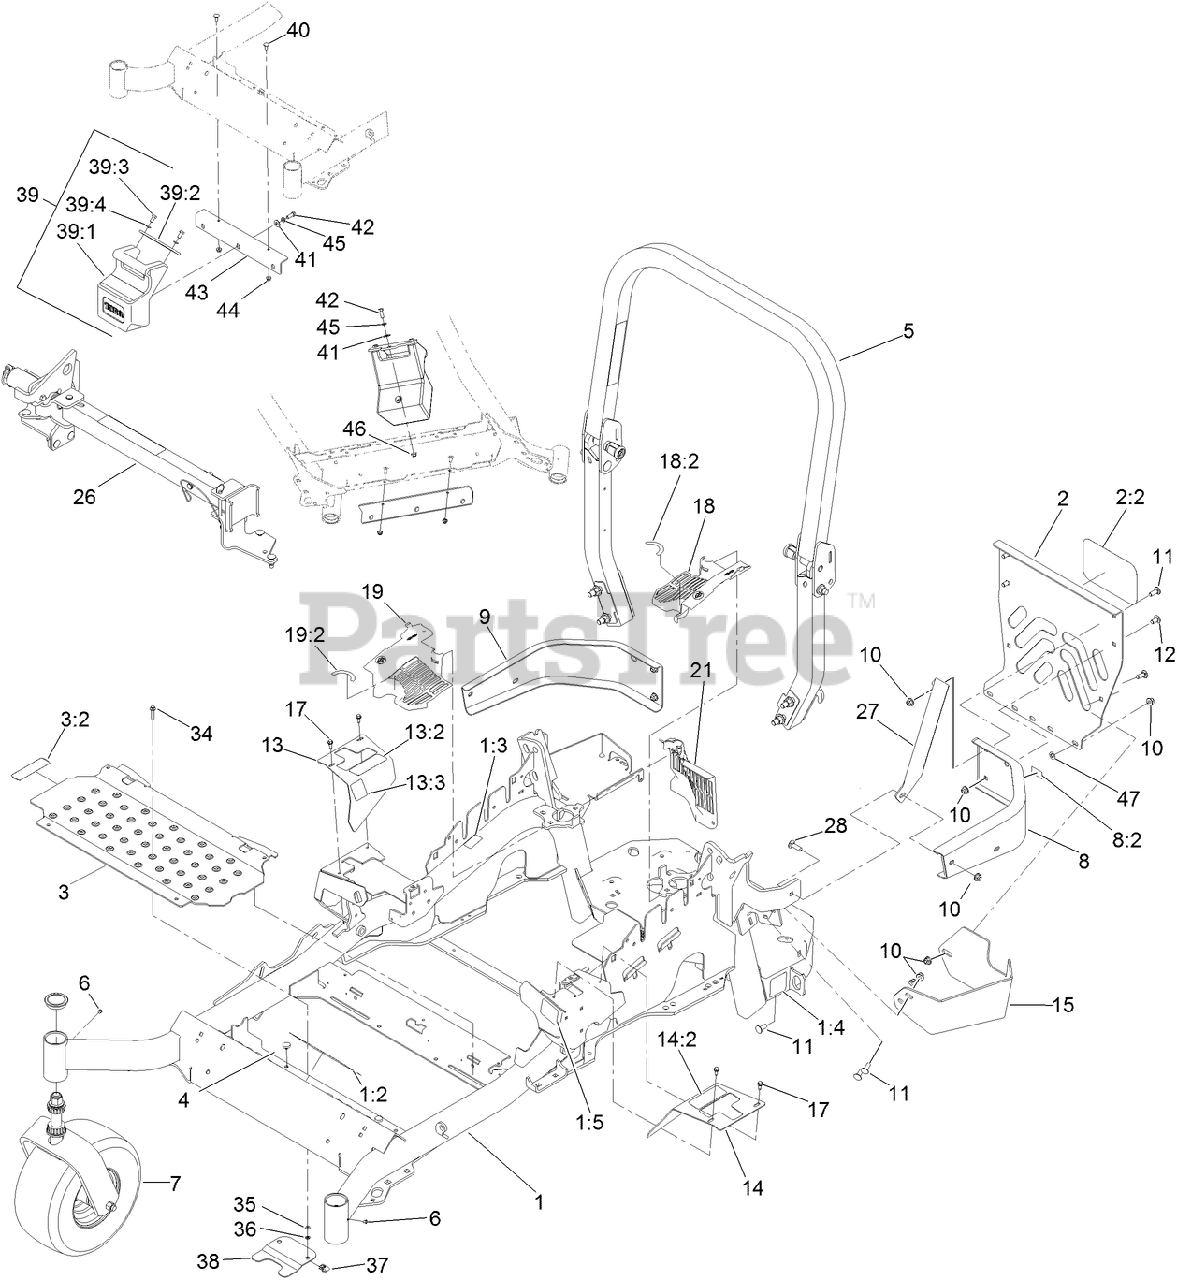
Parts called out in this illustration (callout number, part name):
1	MAIN FRAME ASM
1:2	DECAL-DANGER SLOPE W/ROPS
1:3	DECAL-WARNING
1:4	DECAL-HAZARD, PINCHED FINGER
1:5	DECAL-FUEL FILL, CE
2	REAR GUARD ASM
2:2	DECAL
3	FLOORPAN ASM
3:2	DECAL-MISSING, COVER
4	BUMPER
5	ROPS ASM
7	FRONT CASTER ASM
8	LH REAR BUMPER ASM
8:2	DECAL-WARNING
9	BUMPER-RH
10	NUT-HF, NI
11	SCREW-CARR
12	SCREW-CARR
13	RH MOTION CONTROL COVER ASM
13:2	DECAL-CONTROL, MOTION
13:3	DECAL-PARK BRAKE, CE
14	LH MOTION CONTROL COVER ASM
14:2	DECAL-CONTROL, MOTION
15	GUARD-MUFFLER
17	SCREW-HWH
18	LH HYDRO GUARD ASM
18:2	DECAL-HYDRO OIL
19	RH HYDRO GUARD ASM
19:2	DECAL-HYDRO OIL
21	GUARD-HYDRO, REAR (RH)
26	Z STAND ASM
28	BOLT-CARR
34	SCREW-HHF
35	WASHER-FLAT
36	NUT-RETAINER
38	ADAPTER-CAPTIVE
39	WEIGHT ASM
39:1	WEIGHT-43 LB
39:2	TAB-SUPPORT, WEIGHT
39:3	SCREW-HH
39:4	WASHER-LOCK
40	SCREW-CARR
41	WASHER-FLAT
42	SCREW-HH
43	BRACKET-MOUNT, WEIGHT
44	NUT-HF, NI
45	WASHER-LOCK
46	NUT-HF, NI
47	NUT-PUSH
